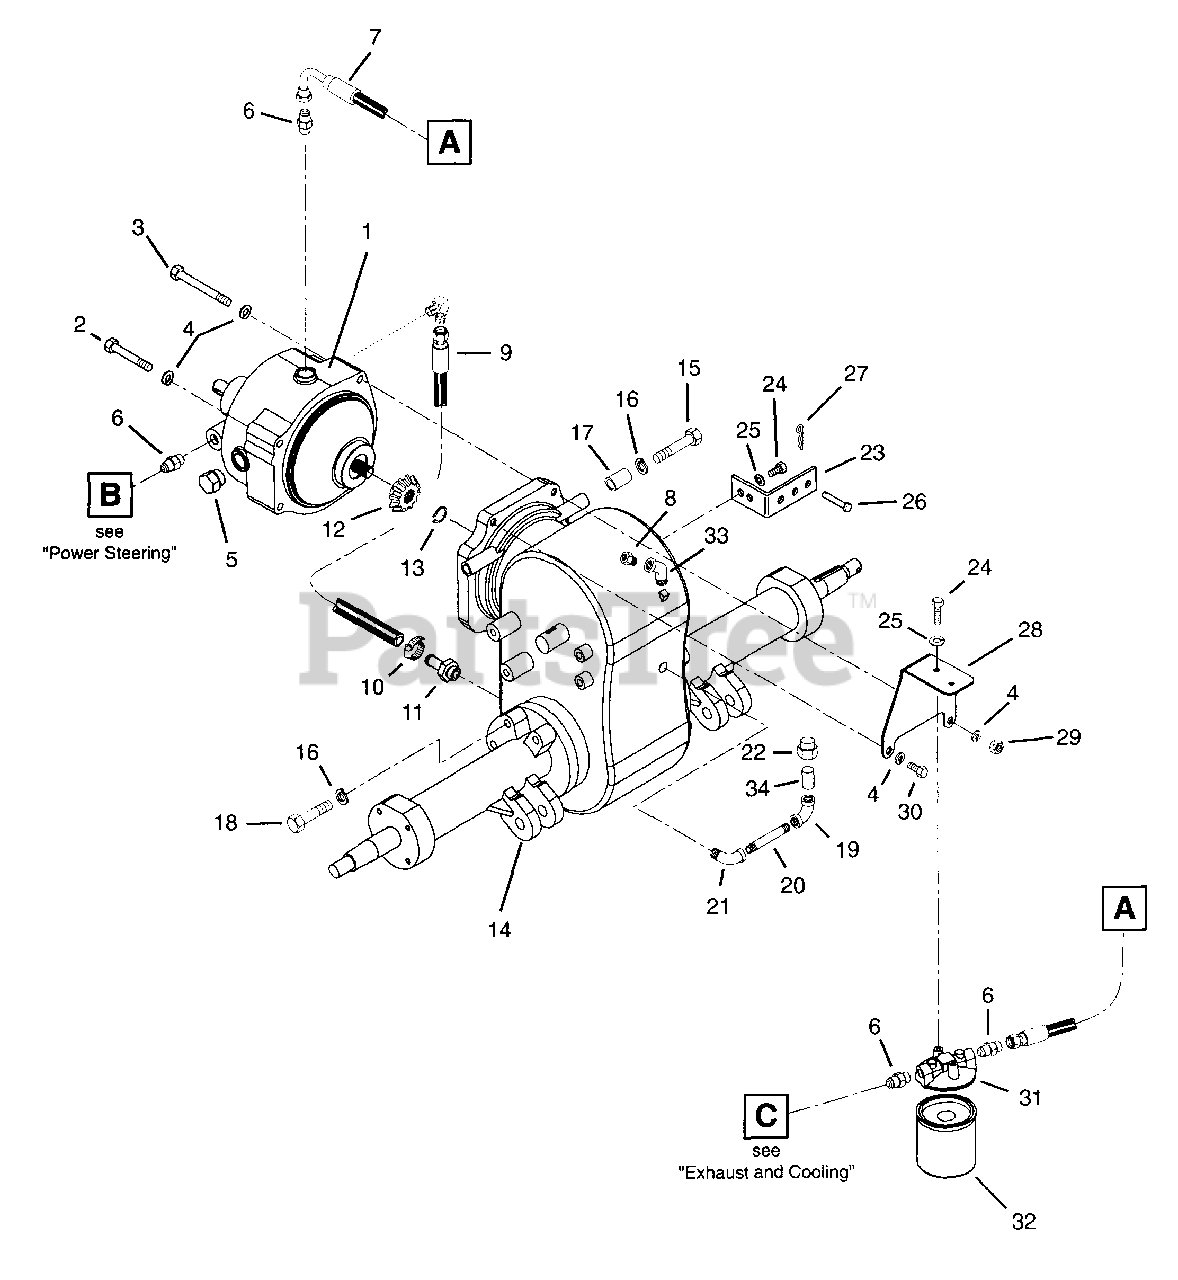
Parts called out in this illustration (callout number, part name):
1	Hydro, Eaton M-11
2	Bolt-Hex .38-16 x 2.75 Grade 5
3	Bolt-Hex .38-36 x 3.50 Grade 5
4	Washer-Locking .38 x .094
5	Plug, 7/8-14 O-Ring
6	Adapter-Pipe
7	Assembly, Hydraulic Hose
8	Plug, Breather 3/8"
9	Assembly, Hydraulic Hose
10	Clamp, .88 Dia. Hose
11	Fitting, Adapter .88-14
12	Gear, Pinion
13	Ring-Retaining-External .375 x .025
14	Transaxle, Peerless
15	Bolt-Hex .50-13 x 2.50 Grade 5
16	Washer-Locking .50 x .125
17	Spacer, Transmission Mount
18	Bolt-Hex .50-13 x 3.00 Grade 5
19	Elbow .375-18
21	Elbow .38 x 90
22	Pipe Cap
23	Plate, Shift
24	Bolt-Hex .25-20 x .50 Grade 5
25	Washer-Locking .25 x .062
26	Pin, Clevis .25 x 1.75
27	Pin-Hair-Internal .08 x .18 x 1.18
28	Bracket, Oil Filter Mount
29	Nut-Locking-Center .38-16
30	Bolt-Hex .38-16 x .75 Grade 5
31	Filter Head
33	Street Elbow, 45 Degree
